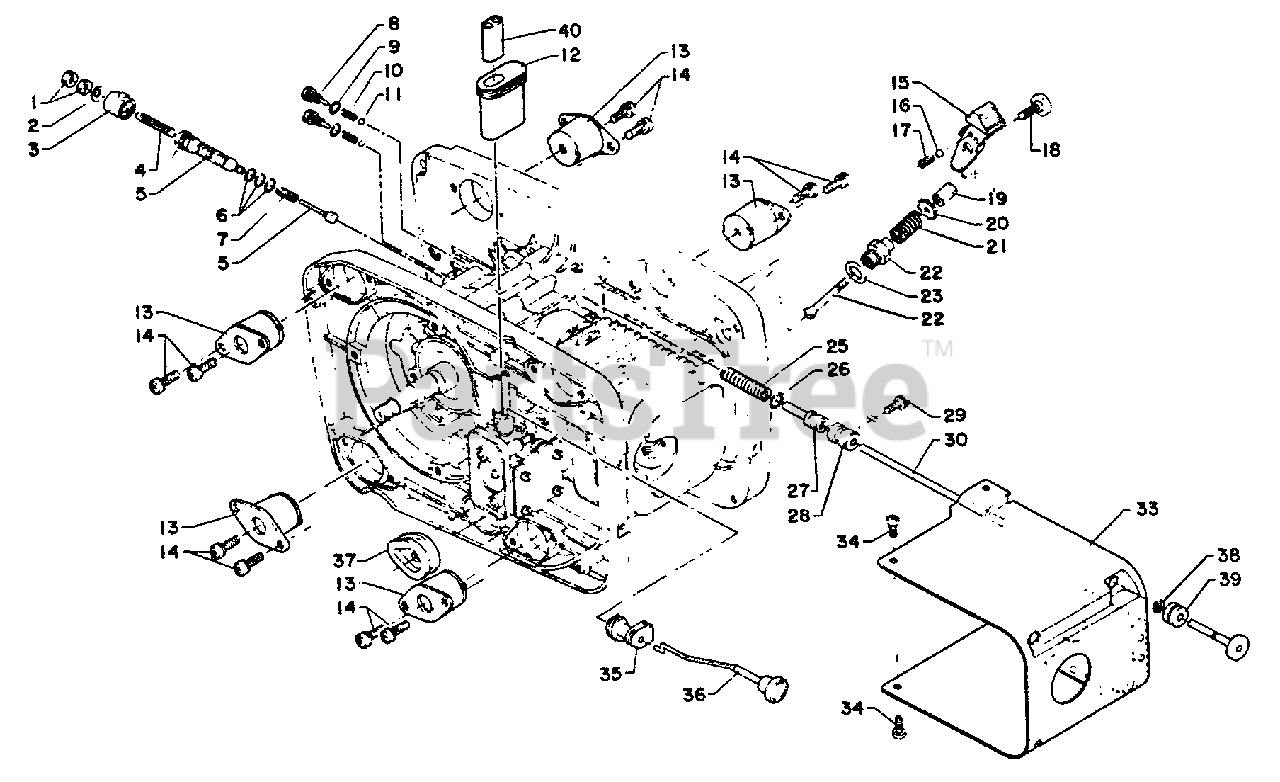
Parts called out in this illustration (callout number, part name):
2	LOCKWASHER
3	DIAL, AUTO-OILER
4	SCREW, ADJUST
5	PUMP KIT
6	O-RING - 5
8	ADAPTER, OIL PUMP
9	O-RING - 4
10	SPRING, VALVE
11	VALVE, BALL
13	CUSHION
14	SCREW - 5X12
15	LEVER, DECOMPRESSION
16	VALVE, BALL
18	SCREW - SET
19	NUT
21	SPRING, VALVE
22	DECOMPRESSION ASSY
23	SEAL
25	SPRING, PUMP
26	O-RING - 6
27	PISTON, OIL PUMP
28	COVER, PUMP PISTON
29	SCREW - 4X12
30	ROD, PUMP
33	COVER, ENGINE
34	SCREW - 4X10
35	GROMMET
36	ROD, CHOKE
37	GROMMET
38	RING, RETAINING - 3
39	GROMMET
40	GUIDE
